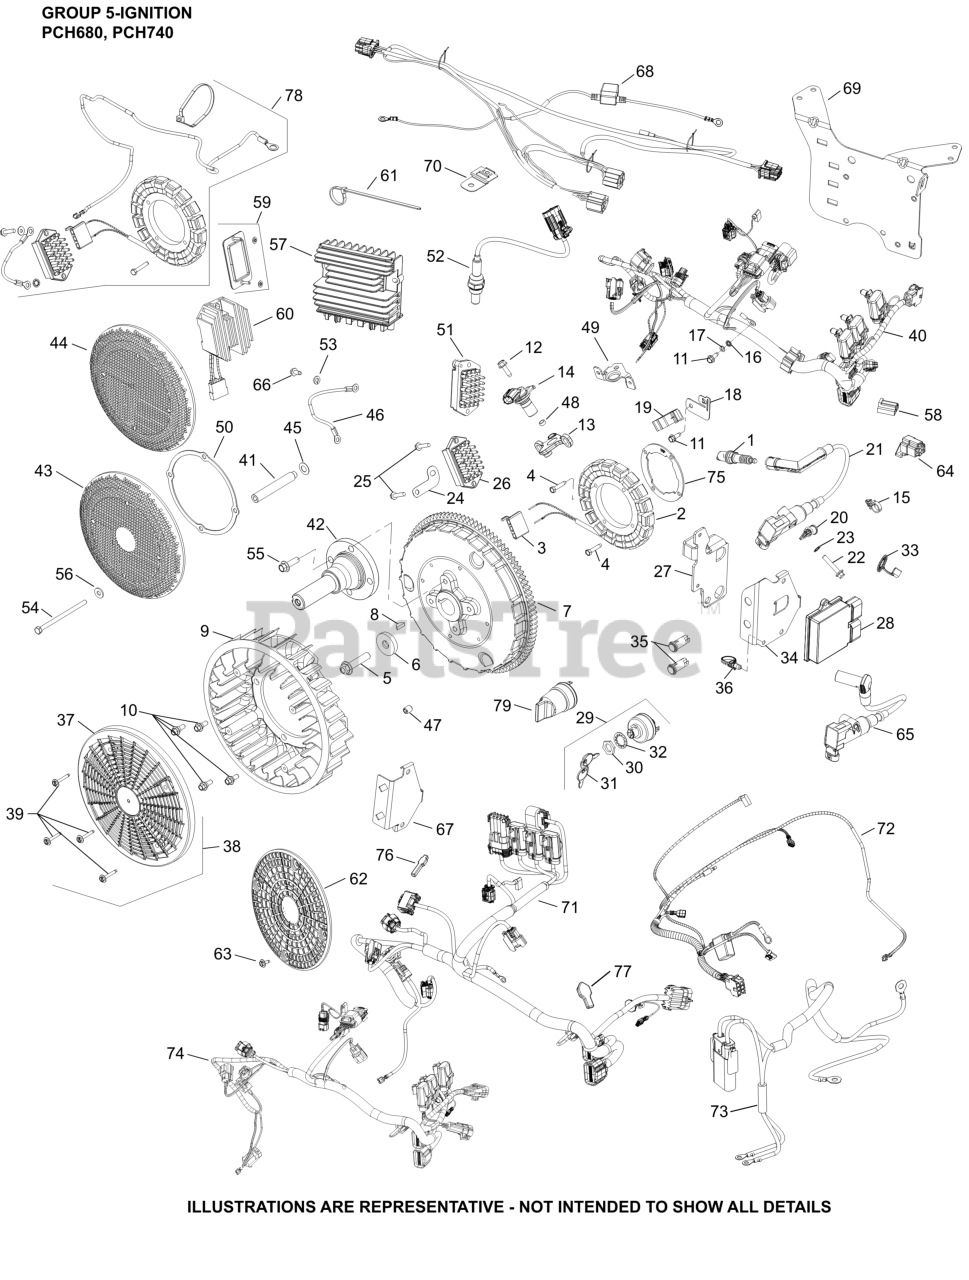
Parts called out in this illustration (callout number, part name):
1	SPARK PLUG, RFI
2	KIT, 15 / 20 AMP STATOR
3	CONNECTOR
4	SCREW, THREAD FORMING
5	SCREW, FLG M10X1.5X45-USE 25 086 361-S
6	WASHER, FLAT 13/32"
7	FLYWHEEL, ASSEMBLY
8	KEY, 3/16" X 5/8"
9	FAN-USE 24 755 253-S
10	BOLT, SHOULDER
11	SCREW, THREAD FORMING
14	SENSOR, SPEED
16	WASHER, INT TOOTH LOCK #10
21	COIL, IGNITION - EFI (RFI/EMC)
22	SCREW, FLG (BLACK) M6X1.0X34
23	WASHER, INT TOOTH LOCK 1/4"
25	SCREW, HEX FLANGE HI-LO
27	BRACKET, ECU
31	KEY, SET OF 2
33	CAP, CONNECTOR
34	BRACKET, WARNING LIGHT
36	TIE, WIRE
37	SCREEN, GRASS
38	KIT GRASS SCREEN
39	SCREW, FLG SEMS M4x.7x25
40	HARNESS, WIRING ASSEMBLY
49	BRACKET, SENSOR
51	REGULATOR, RECT (20-30AMP, FW W/OVP)
66	SCREW, THREAD FORMING
NI	MODULE, ECU PCH740
NI	KIT, KEY SWITCH (SNAP-IN)
NI	CLAMP, INSULATED
NI	LIGHT, INDICATOR
NI	CLIP, CABLE (KM)
